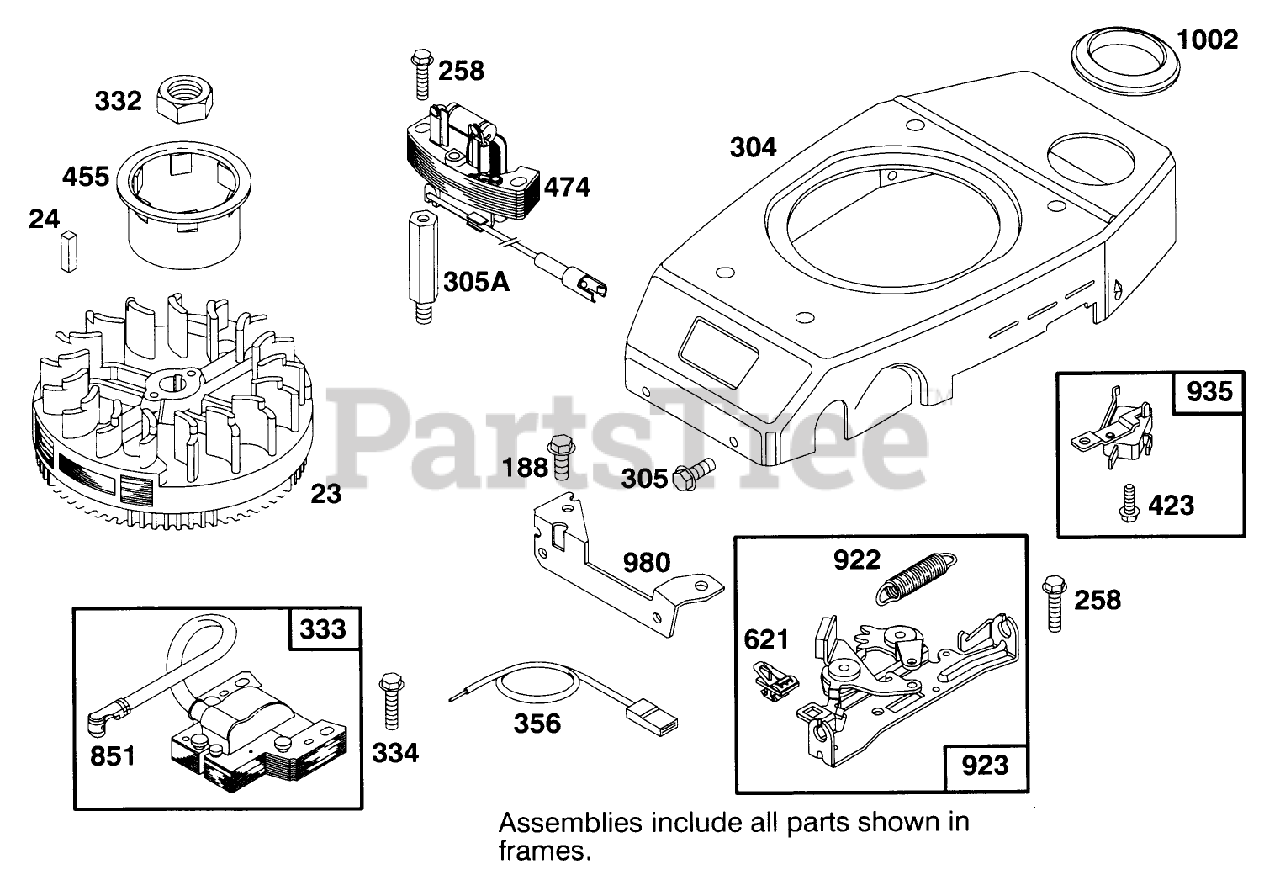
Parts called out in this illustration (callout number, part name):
23	FLYWHEEL - MAGNETO
24	KEY - FLYWHEEL
305	SCREW - HEX HEAD
332	NUT - HEXAGON
334	SCREW - SEM
356	WIRE - GROUND
621	STOP SWITCH
980	BRACKET-BLOWER HSG
